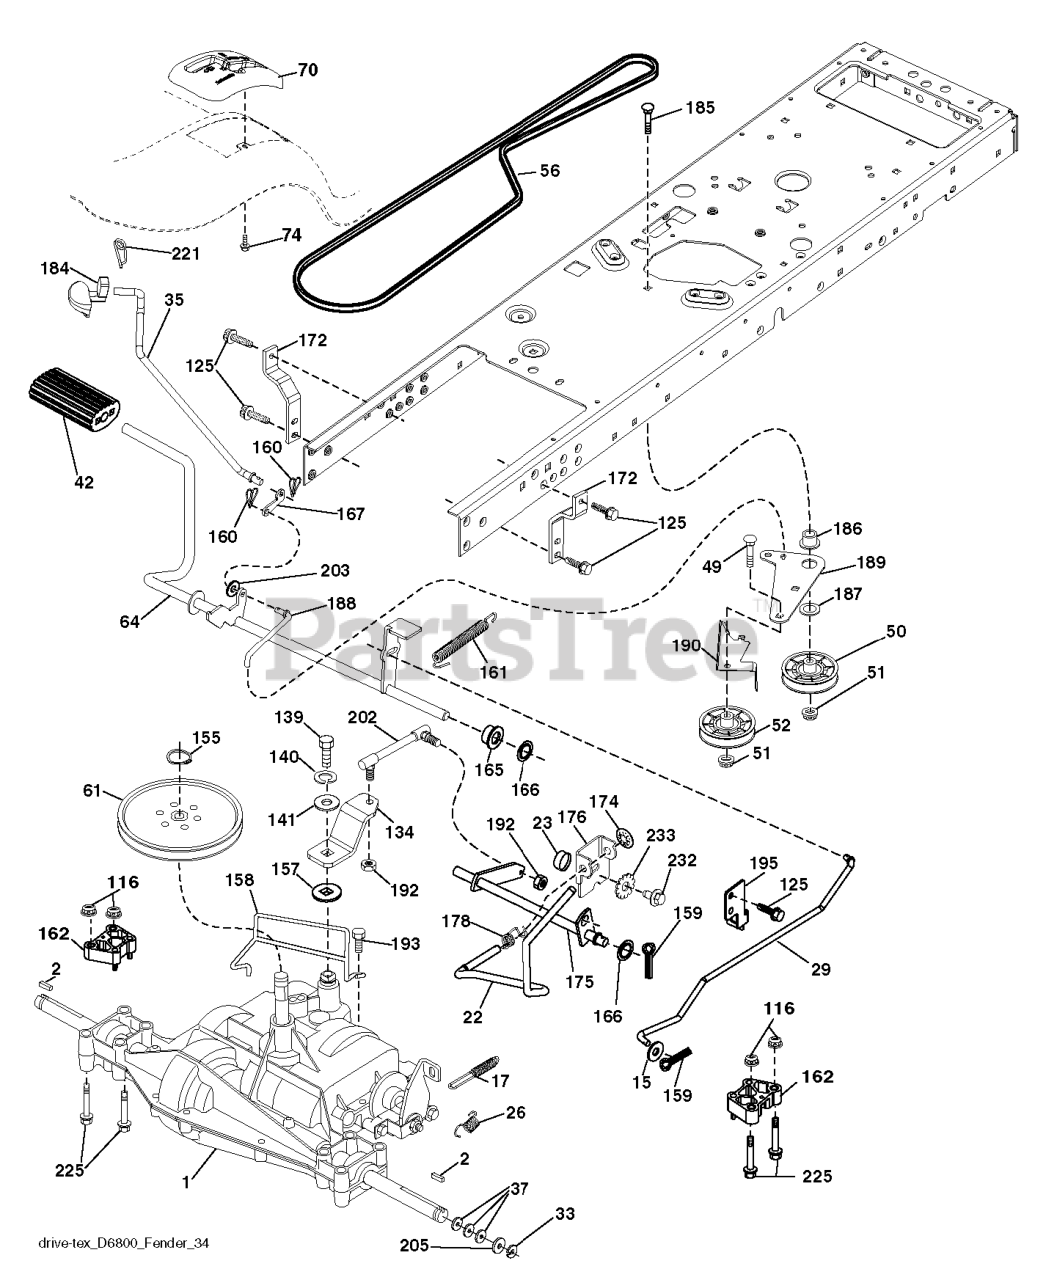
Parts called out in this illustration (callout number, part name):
2	SQUARE KEY
15	WASHER
17	SPRING.BRAKE.PEERLESS.TEX
22	ROD.SHIFT.FENDER.TLT.2006
23	KNOB.DUCKHEAD.1/2
26	SPRING.BRAKE.RTN.GR.DR
29	ROD.BRAKE.PEERLESS
35	ROD.CNTRL.PARK.PREDATOR.LT.TEX
42	PEDAL COVER T
50	IDLER.FLAT.910.OFFSET
51	NUT LOCK FLG 3/8-16 UNC
52	IDLER.V-GROOVE.910.OFFSET
56	V-BELT.TRACTOR.DRIVE.P
61	PULLEY TRANS
64	SHAFT.ASM.PEDAL.BRAKE.
70	CONSOLE.SHIFT.STL.6SP.GREY
74	SCREW.HI-LO.CONSOLE
116	NUT LOCK HEX FLANGE 5/16-18
125	SCREW
134	ARM.SHIFT.
139	BOLT 1/4-28X3/4
140	LOCKWASHER
155	RETAINING RING LT
157	WASH-SHFT PLT LT
158	KEEPER.PMS.18/20.D4365
159	COTTER PIN
160	RETAINER CLIP
161	SPRING.RETURN.CLUTCH.2006
162	SPACER.TRANSAXLE.18&22
165	BUSHING.SHAFT.BRAKE.HAND
166	NUT.PUSH.625.2006
167	LATCH.BRAKE.SPRING
172	STRAP.TRQ.LH.GEAR.DRIV
174	NUT.PUSH.500.2006
175	SHAFT.ASM.SHIFT.
176	ARM.CLEVIS.ROD.SHIFT
178	SPRING.SHIFT.GT2006
184	HANDLE PARKING BRAKE
186	SPACER.RETAINER
187	WASHER 12/32X2X10GA
188	RP.LINK.CLUTCH.GROUND.DRIVE
189	BELLCRANK.GROUND.DRIVE.TEX.
190	KEEPER.BELLCRANK.DRIVE
192	NUT LOCK CENTER 1/4 -28 FNTHD
193	SCREW 5/16"
195	BRKT.ROD.BRAKE.PEERLES
202	LINK.TRANSAXLE.D6800.18/20"TEX
203	WASHER
221	RETAINER.SPRING.CLIP.H
225	BOLT.HEX.FLNG.5/16-18X3.75
232	BOLT FIN HEX 7/16-14 X 1
233	WASHER SERRATED
